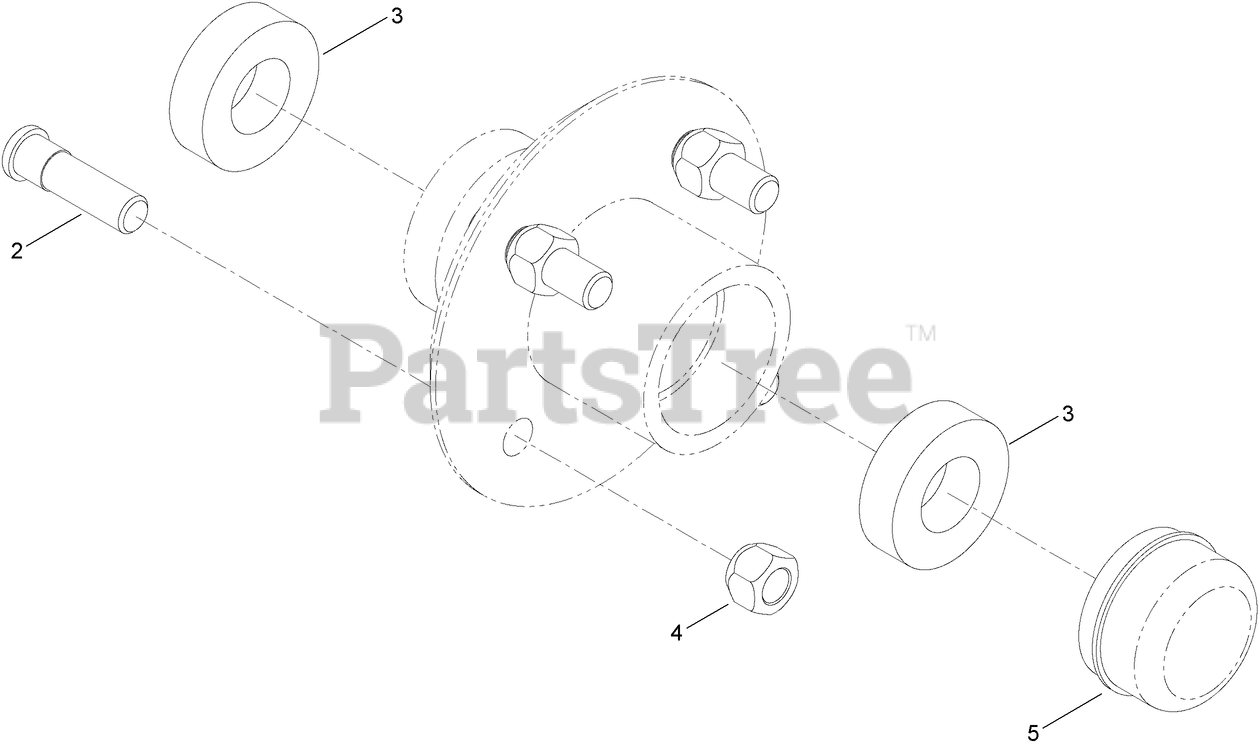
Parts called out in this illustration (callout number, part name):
2	STUD-WHEEL
3	BEARING-ROLLER
4	NUT-LUG
5	CAP-DUST
